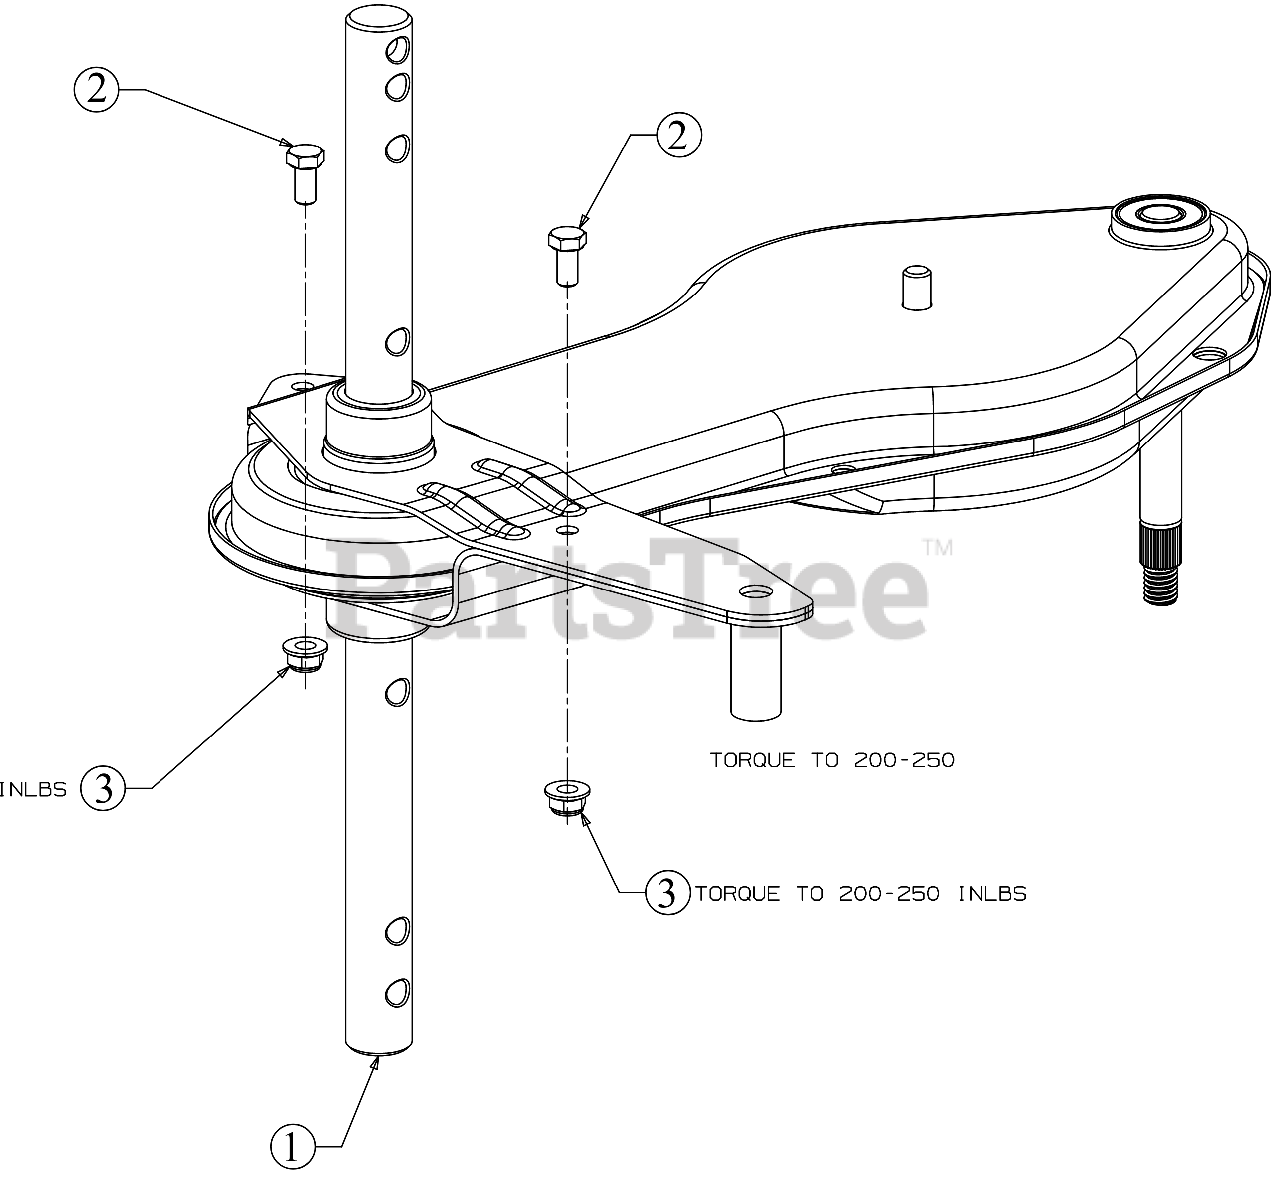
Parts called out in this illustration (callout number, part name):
1	CHAIN CASE ASSEMBLY
2	SCREW 5/16-18X .625 GR5
3	FLANGE LOCK NUT 5/16-18
